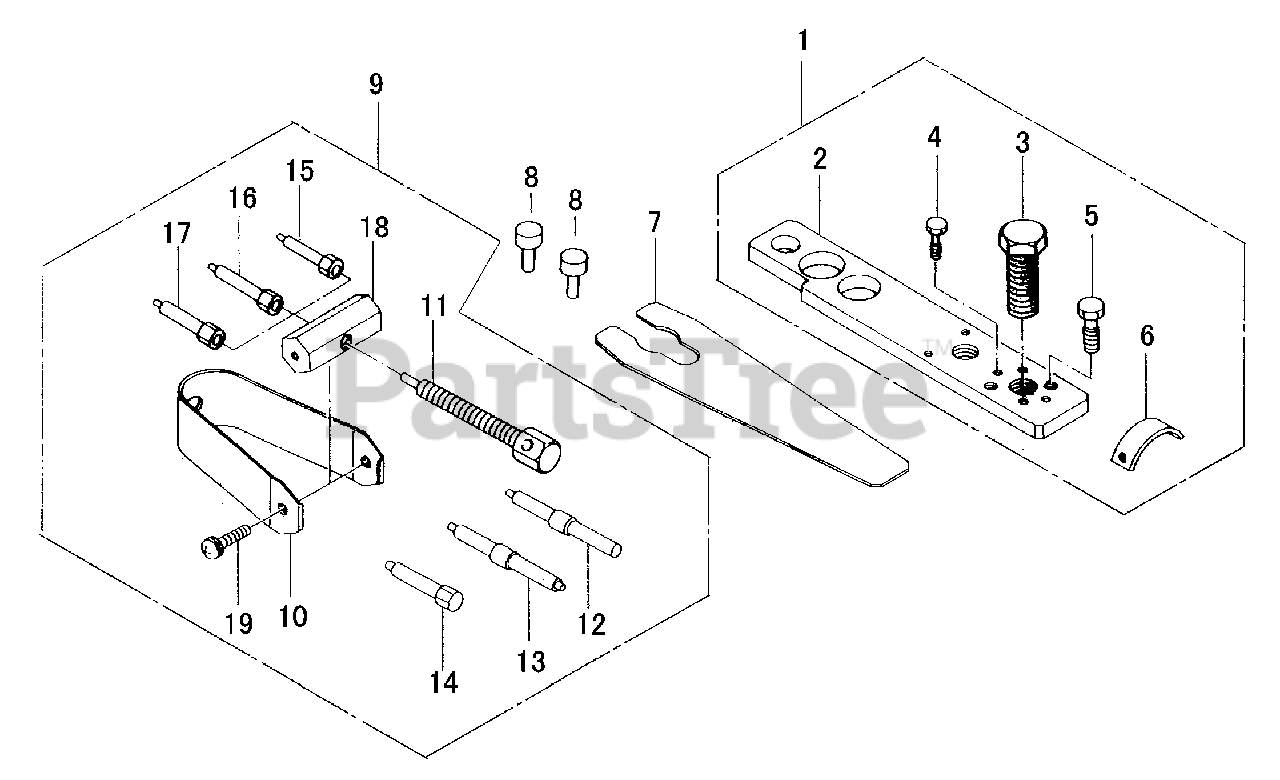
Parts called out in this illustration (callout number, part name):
2	LEVER
3	BOLT, CENTER
4	BOLT
5	BOLT
6	GAUGE, GAP
7	SPANNER WRENCH, FLYWHEEL
8	STOPPER
9	PULLER ASSY
11	BOLT
12	PING, GUIDE
13	PING, GUIDE
14	PING, GUIDE
15	PIN, ADAPTOR
16	PIN, ADAPTOR
17	PIN, ADAPTOR
18	BOSS
